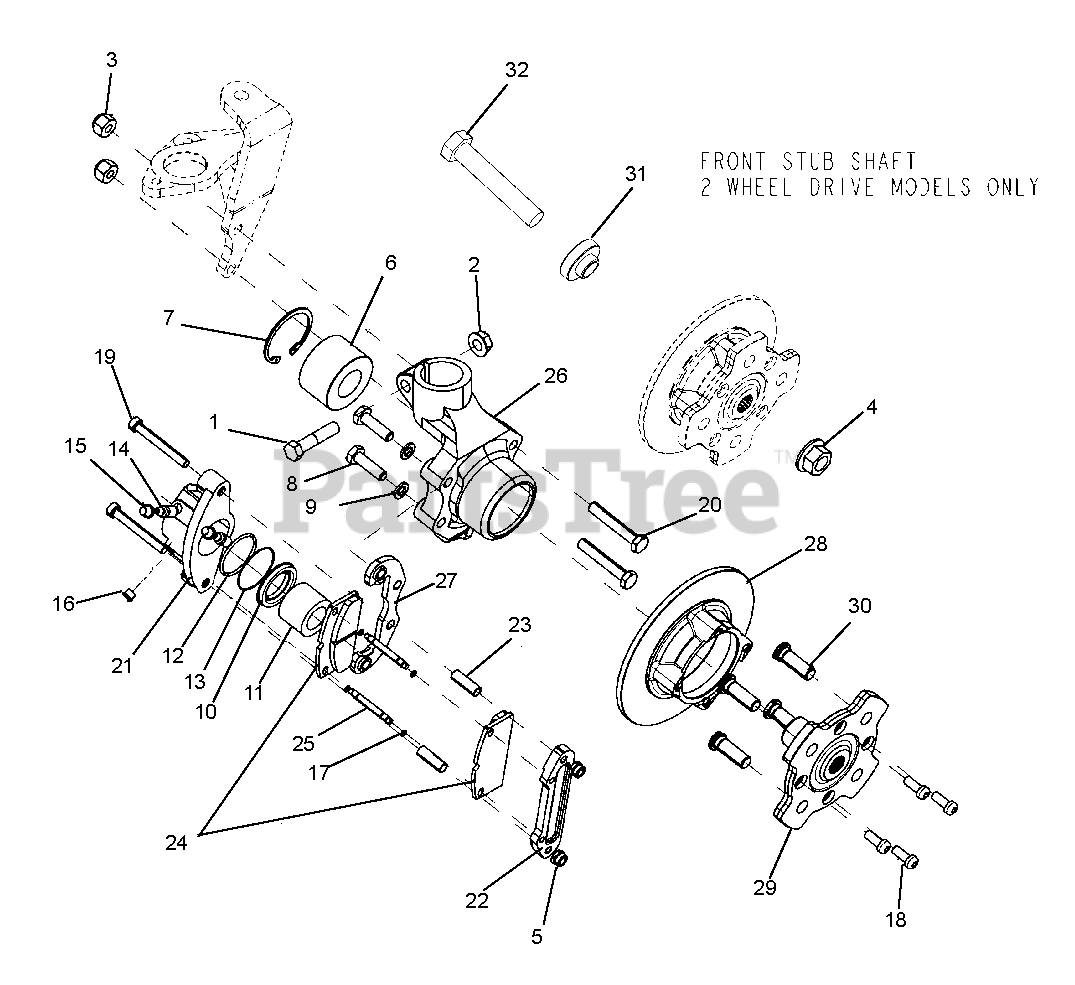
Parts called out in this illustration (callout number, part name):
1	BOLT, HEX .38-16 X 2.00 GR8 YWZC
2	NUT, LOCKING NYLON .38-16
3	NUT, HEX NYLOCK M10 X 1.5 PLT
4	NUT, HEX M16 X 1.5 TOP LOCK PLT
5	NUT, M8
6	BALL BEARING 60,05 X 30 X 37
7	SNAP RING
8	SCREW, M 10 X 1.25 X 35
9	M 10 WASHER
10	DUST BOOT RING
11	CAP
12	SEALING RING
13	RUBBER DUST BOOT
14	BLEEDER SCREW
15	BOOT
16	PLUG
17	ELASTIC RING
18	SCREW, M8 X 20
19	SCREW, M8 X 65
20	HHS M10 X 1.5 X 50 PLT
21	CALIPER BODY
22	REACTION BRACKET
23	SPACER
24	BRAKE PAD KIT (COMP. 2 WHEELS)
25	PIN
26	WHEEL PIVOT Rev. 2
27	CALIPER CLAMPING PLATE
28	DISC BRAKE
29	CMEX FLANGE WITH STUDS
30	STUD
31	SPACER, STUB BOLT
32	BOLT, HEX M16-1.5 X 90 X 8.8 YWZC
